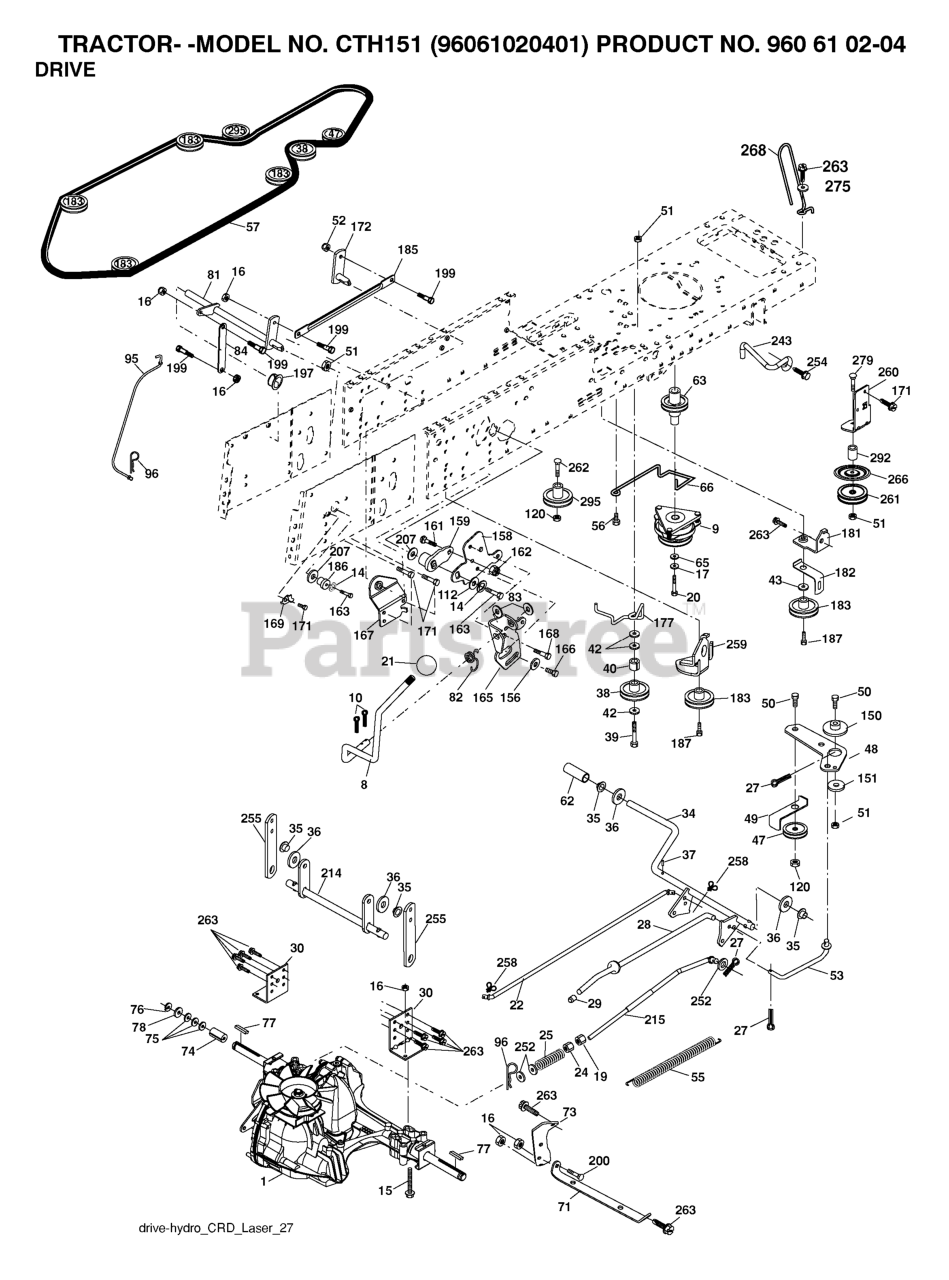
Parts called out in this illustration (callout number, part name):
8	ROD SHIFT FENDER ADJUST LT
9	CLUTCH.ELECTRIC.OGURA.EURO.
10	PIN COTTER
14	LOCKWASHER
15	BOLT HEX 5/16-18 GR 5
16	NUT.71038.31-18.HEX.NYLOCK
19	NUT
20	BOLT HEX 7/16-20X4-1/4"
21	KNOB.DUCKHEAD.1/2
22	ROD
24	NUT
25	SPRING BRAKE ROD
27	COTTER PIN
28	ROD, PARKING BRAKE
29	CAP
30	BRKT, TRNSXLE MNT 20"
34	SHAFT, FOOT PEDAL
35	BEARING.NYLON
36	WASHER LT
37	DRIVE PIN
38	PULLEY.FLAT
42	WASHER
43	WASHER T
47	IDLER PULLEY
48	BELLCRANK, CLUTCH
49	RETAIN BELT
50	BOLT.3/8-16X1.50
52	LOCKNUT
53	LINK.CLUTCH.7.66.2005
55	SPRING, RETURN LT
56	SCREW.3/8-16
57	V-BELT 113"
62	PEDAL COVER T
63	PULLEY.ENGINE.CVX.LT
65	LOCKWASHER
66	KEEPER BELT ENGINE
71	STRAP TORQUE LH HYDRO
73	STRAP TORQUE RH HYDRO
74	SPACER AXLE
77	SQUARE KEY
81	ASM.CROSS.SHAFT.REAR.CRD.0510
82	SHIFT SPRING
83	WASHER
84	LINK.PNT.TRANSAXLE.0510.CRD
95	LINK
96	RETAINER M
112	WASHER LT
120	NUT LOCK FLG 3/8-16 UNC
150	BUSHING.BELLCRANK.GRD.DR
151	WASHER 12/32X2X10GA
156	WASHER.SRRTD.5/16
158	BRACKET
159	RB HUB.SHIFT
161	BOLT
162	NUT.CROWNLOCK.1/4
163	BOLT
165	RP BRACKET
166	CAPSCREW.HXHD.FLG.5/16-18X.625
167	BRACKET.SUPT.SHIFT.CRD
168	BOLT.SHOULDER.5/16-18X
169	PLATE.FASTENING.CROSS.SHAFT
171	SCREW LT
172	LINK
181	BRACKET
182	BELT GUIDE
183	PULLEY.V-IDLER.GRND.DR
185	LINK
186	HUB.TAPERED.ROUND.CRD
187	BOLT.5/16-18X1.25
197	NYLINER SNAP 5/8" ID
199	BOLT SHOULDER 5/16-18 UNC
200	BOLT
207	WASHER NYL
214	LEVER
215	ROD
243	BRACKET, ANTI-ROTATION
252	WASHER
254	SCREW 3/8-16X1
255	SHAFT
258	CLIP RETAINER
259	BRACKET
261	FLAT IDLER PULLEY
263	SCREW, 3/8-16X3/4
266	PROTECTOR
268	GUARD MUFFLER
275	WASHER
279	BOLT
292	SPACER
295	PULLEY IDLER COMPOSITE
